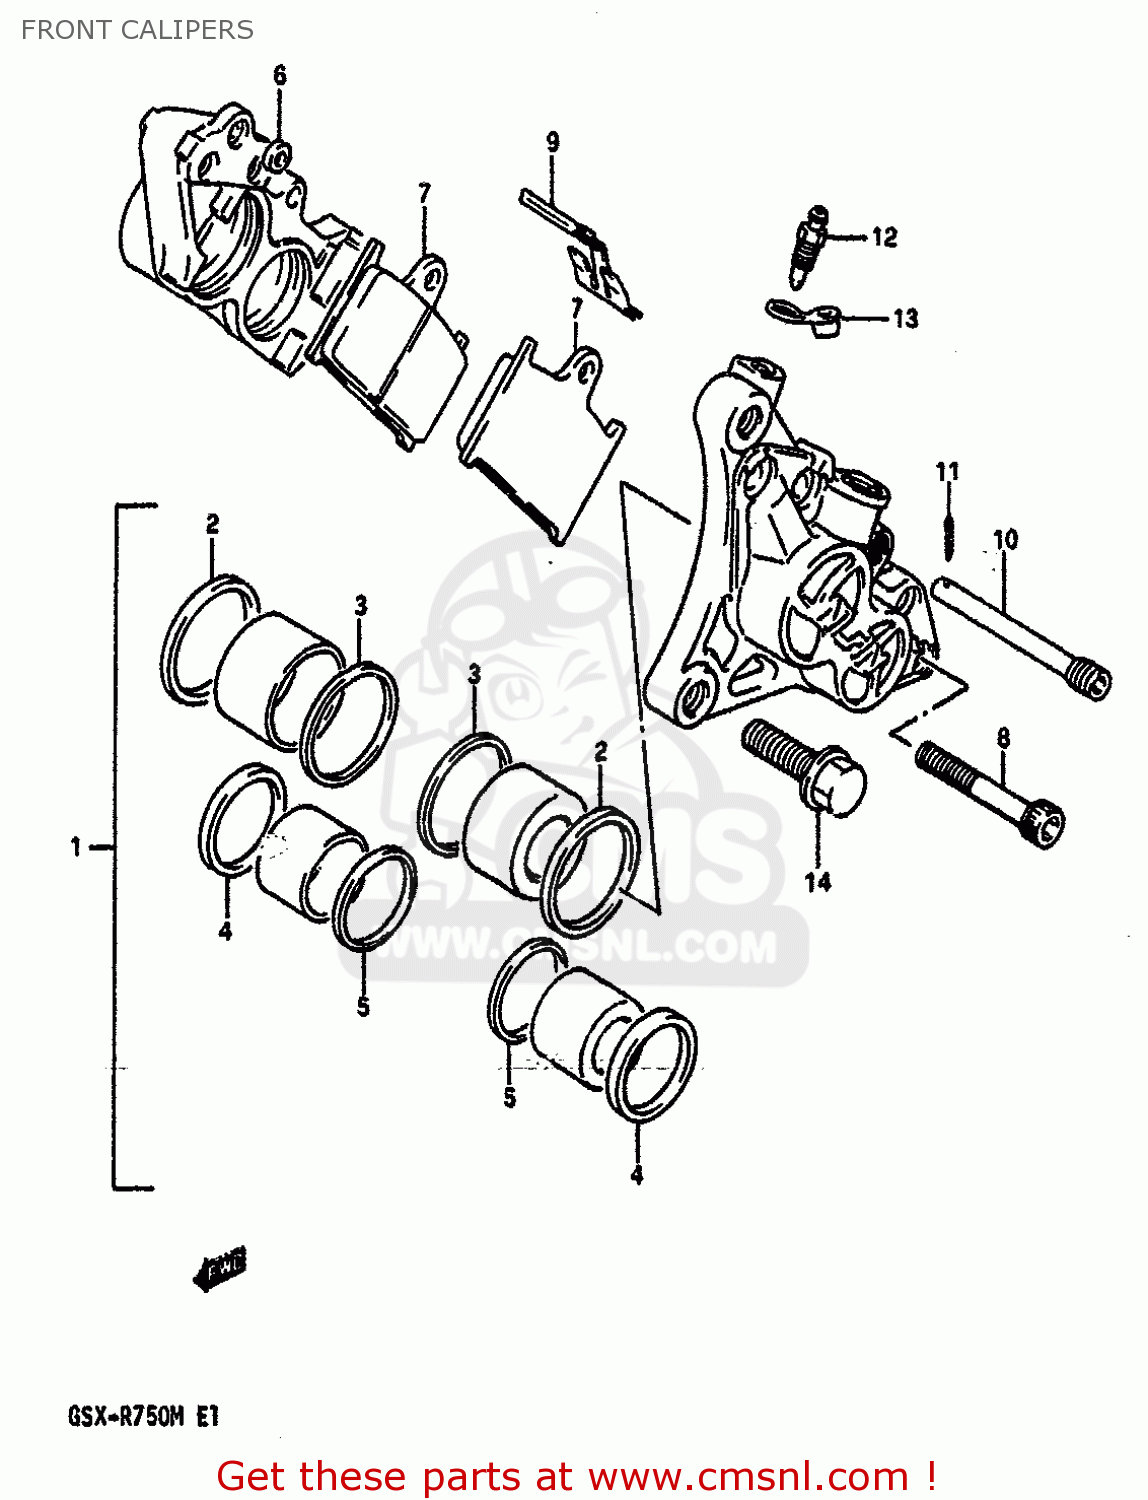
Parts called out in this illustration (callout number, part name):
1	PISTON SET
2	SEAL,PISTON
3	BOOT,PISTON
4	SEAL,PISTON
5	SEAL
6	SEAL
7	PAD,BRAKE
8	BOLT
9	SPRING
10	PIN,HANGER
11	COTTER PIN
12	BLEEDER
13	CAP,BLEEDER
14	BOLT 10X30
